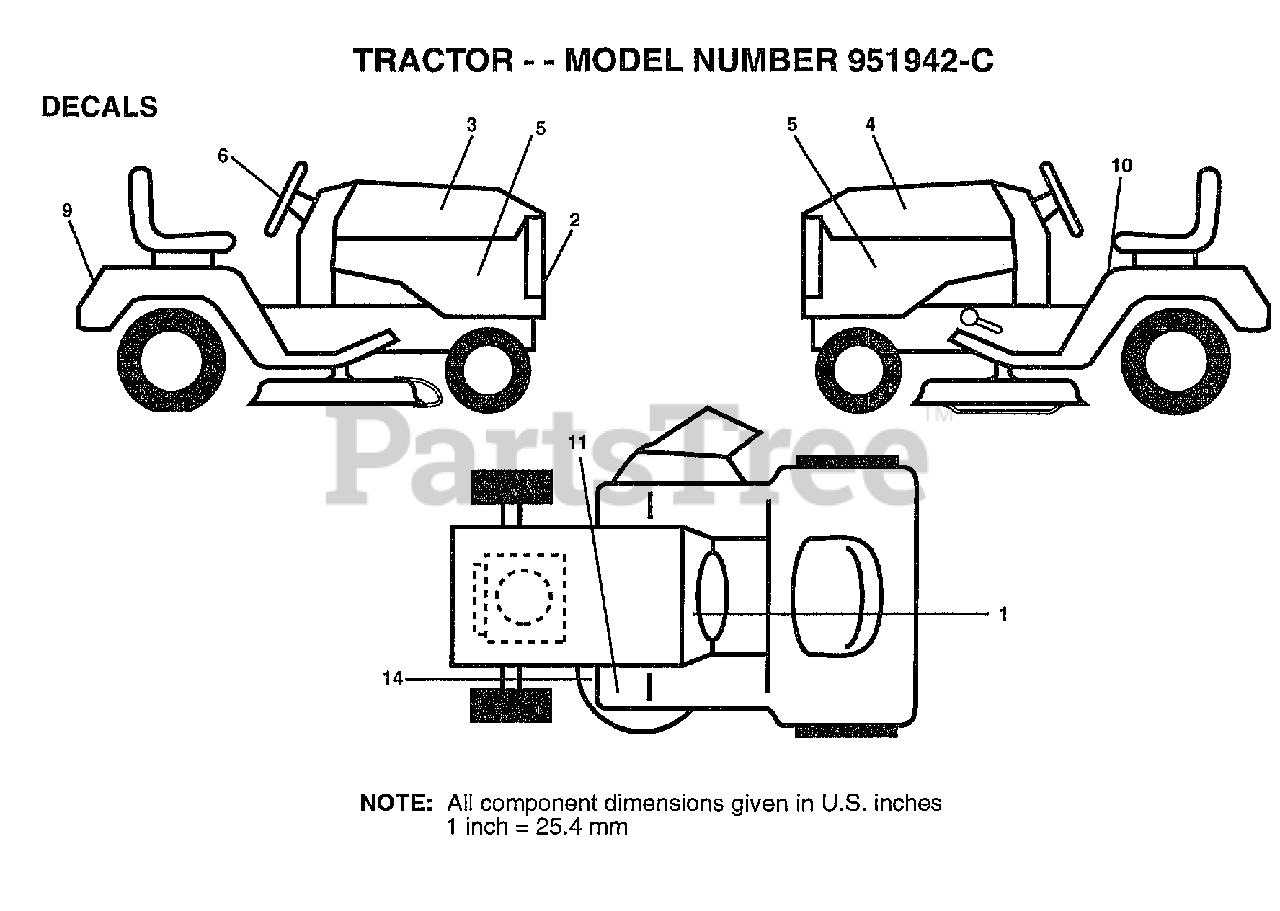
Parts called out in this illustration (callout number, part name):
1	DECAL.DASH.INST.
2	DECAL.GRILL.YARDP
4	DECAL HOOD LH
5	DECAL.PANEL.SIDE
6	DECAL.INS.WHL.STG
10	DECAL
14	"DECAL.V.BELT.44"""
